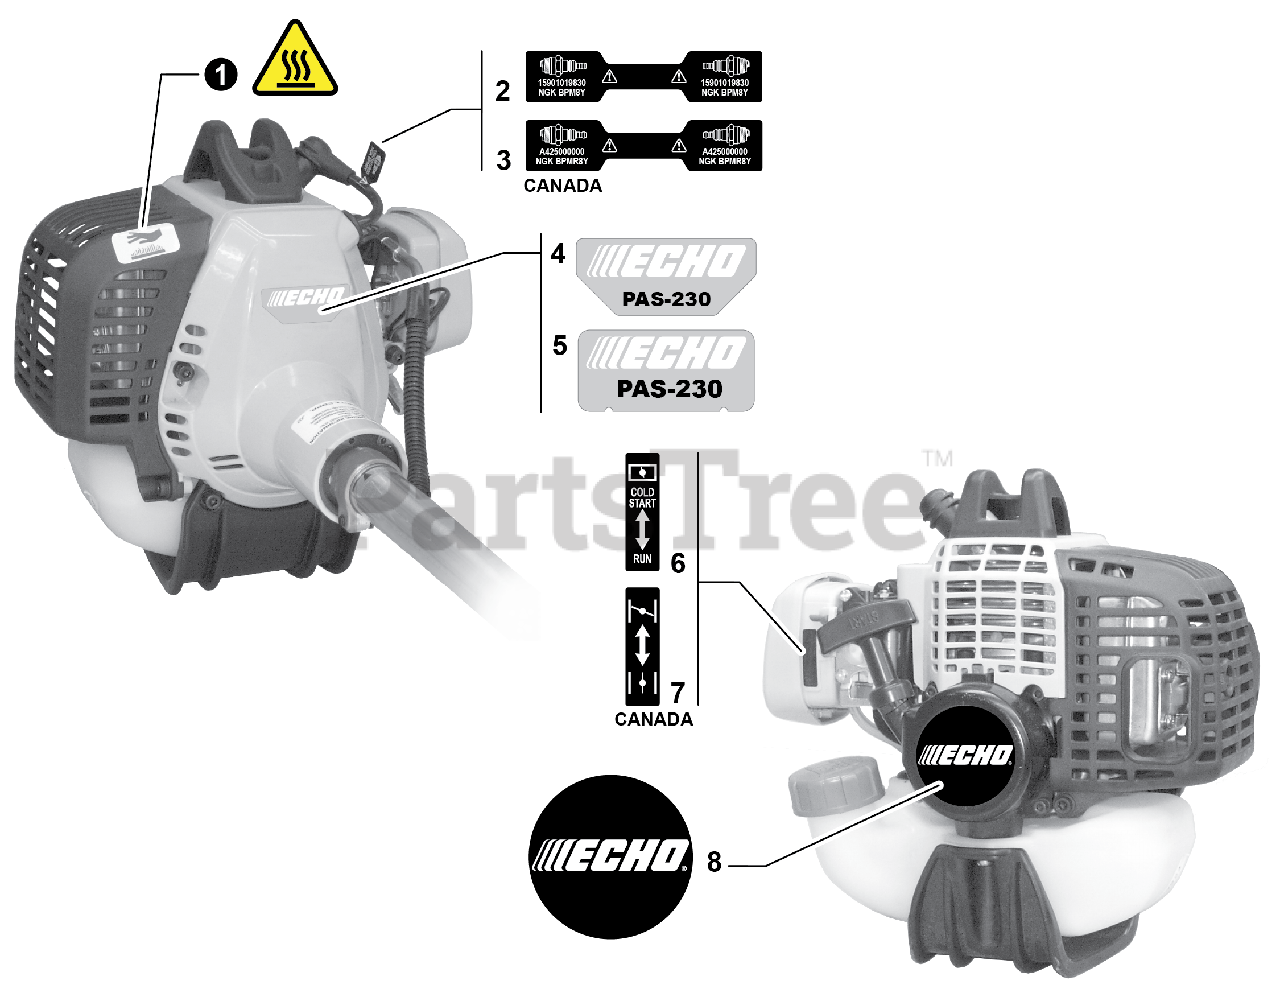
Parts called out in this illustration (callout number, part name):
1	LABEL, CAUTION - HOT
2	LABEL, SPARK PLUG - BPM8Y
3	LABEL, SPARK PLUG - BPMR8Y
4	LABEL, MODEL - PAS-230
5	LABEL, MODEL - PAS-230
6	LABEL, CHOKE
7	LABEL, CHOKE
8	LABEL, RECOIL STARTER
